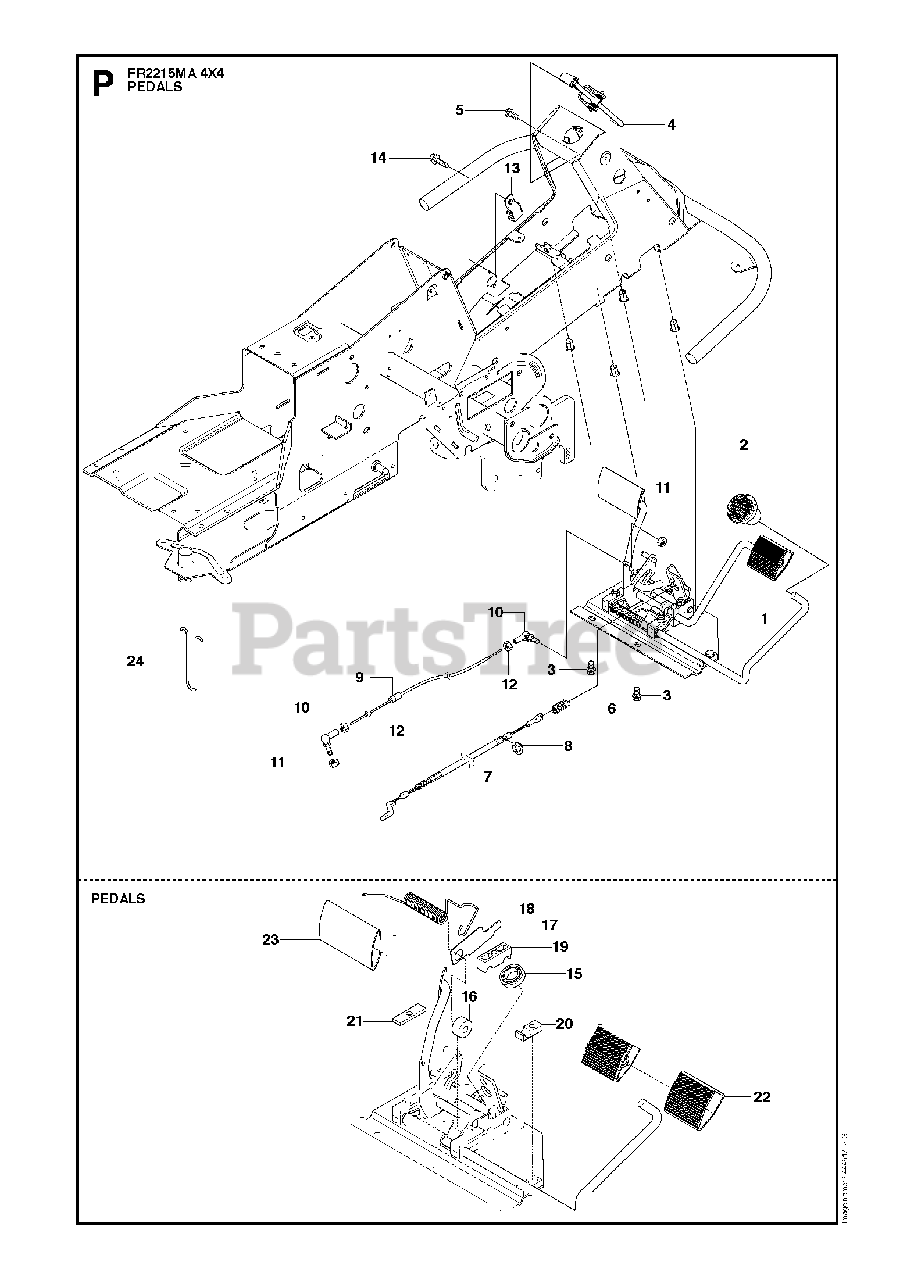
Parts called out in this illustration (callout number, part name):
1	PEDAL ASSEMBLY
2	KNOB
4	BRAKE LEVER ASSY
7	RP WIRE
9	CONTROL CABLE
10	CONNECTOR
11	LOCKNUT M5
15	BALL BEARING 6002-2RS1
16	ROLLER
17	PLATE
18	SPRING
19	PEDAL SHAFT CLAMP
20	SUPPORT
21	PLATE
22	PEDAL RUBBER
23	PEDAL RUBBER, SF
24	CABLE HOLDER
